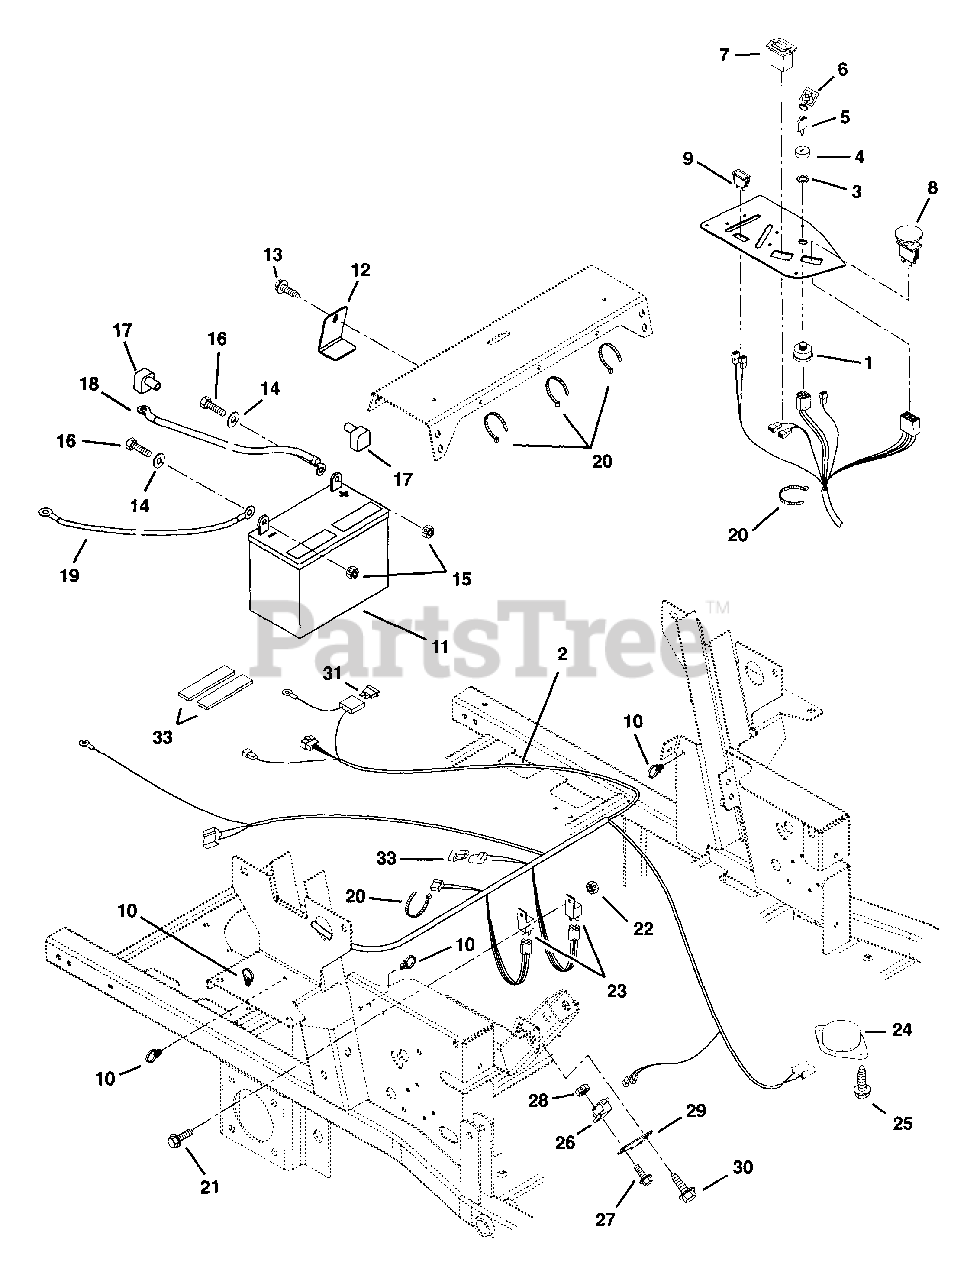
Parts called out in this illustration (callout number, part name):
1	Key Switch
2	Harness Kohler
3	Nut-Panel .562-24
4	Cap-Ignition Switch
5	Ignition Switch Key
6	Key Chain
7	Hour Meter
8	Switch-Clutch With Retainer Ring
9	Light-Indicator
10	Tube Clip .75
11	Battery with Tube
12	Clamp-Battery
13	Screw-Tapping .25-20 x .50 Hex Washer Head
14	Washer-Flat-Steel .281 x .620 x .065
15	Nut-Locking-Center .25-20
16	Bolt-Hex .25-20 x .75 Grade 5
17	Insulator
18	Start Cable 22"
19	Ground Cable
20	Cable Tie
21	Screw-Machine 10-24 x .50 Hex Washer Head
22	Nut-Locking-Nylon 10-24 With Insert
23	Relay
24	Seat Switch
25	Screw-Tapping 12-24 x .50 Hex Washer Head
26	Switch-Single Pole
27	Screw-Machine 10-24 x .75 Hex Washer Head
28	Nut-Locking-Nylon 10-24 With Insert
29	Plate-Switch
30	Screw-Tapping .38-16 x .50 Hex Washer Head
32	Molded Diode Plug-Black 1-Amp
33	Pad-Battery
